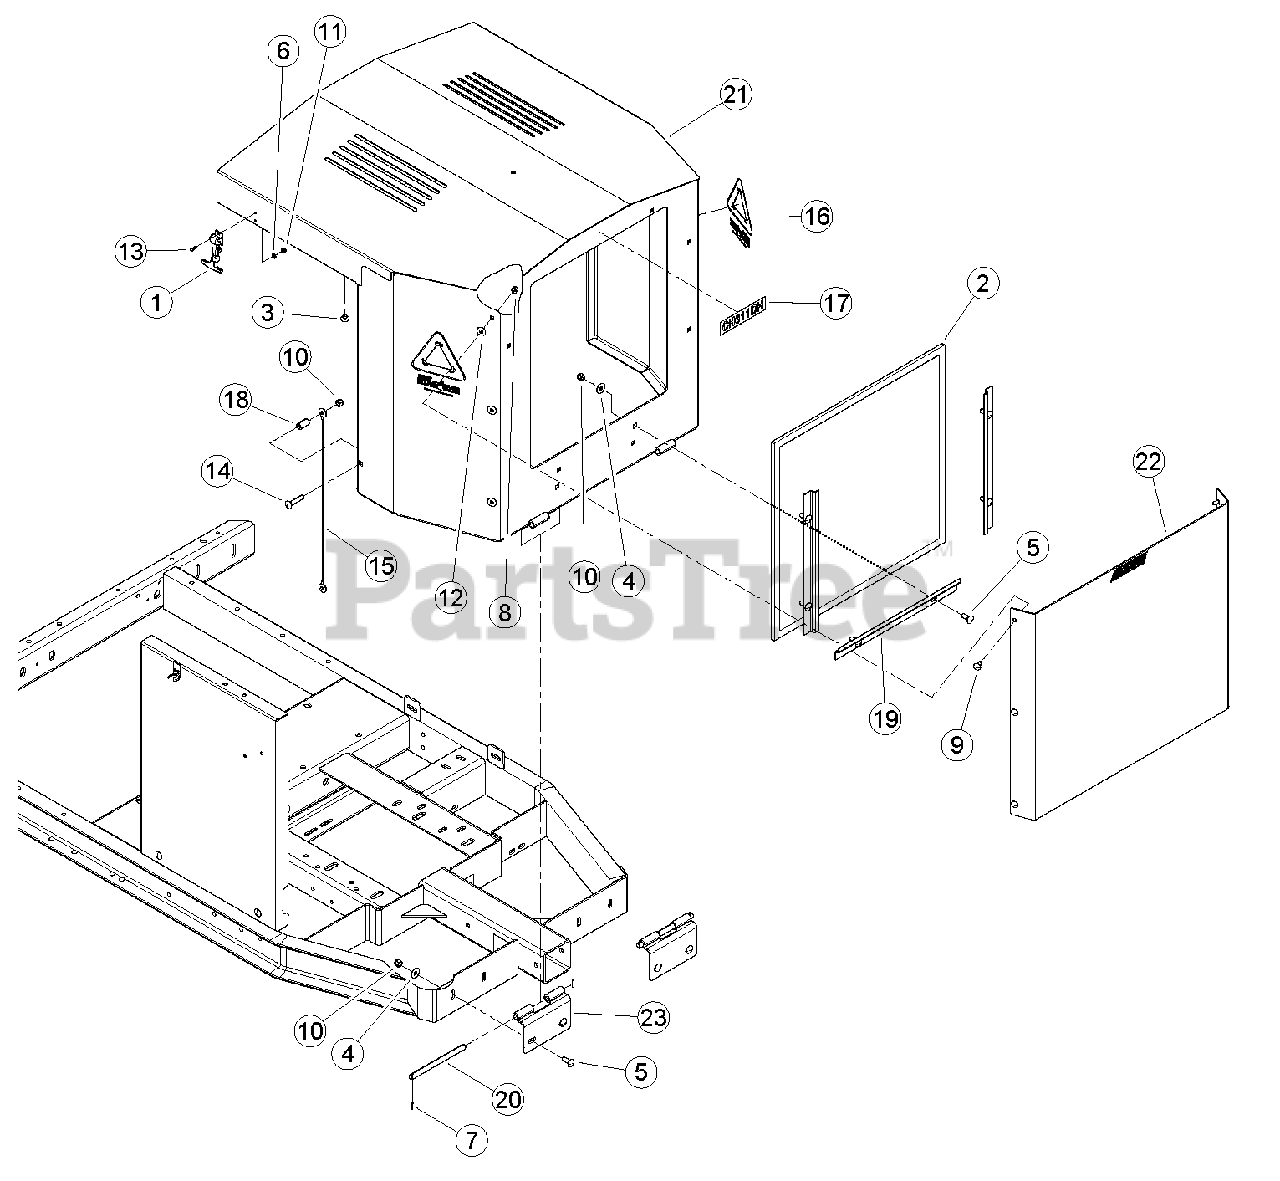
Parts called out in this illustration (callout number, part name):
1	LATCH, FLEXIBLE DRAW
2	SCREEN, RADIATOR INLET
3	BUMPER, RUBBER
4	WASHER, 3/8 FLAT ZP
5	BOLT, 3/8 X 1 CRG GR5 NC ZP
6	WASHER, 3/16 FLAT ZP
7	ROLL PIN, 5/32 X 3/4" PLAIN
8	NUT, 5/16 NE NYLOCK ZP
9	BOLT, 5/16 X 3/4 CRG GR5 NC ZP
10	NUT, 3/8 NE NYLOCK ZP
11	NUT, 10/24 NYLOCK TYPE NM, ZP
12	WASHER, 5/16"ID 7/8"OD NYLON FLAT
13	SCREW, 10-24 X 1/2 MCH PAN HD,PH ZP
14	BOLT, SHOULDER 1.88" LONG CRG GR5 ZP
15	LANYARD, STEEL W/PVC 1/8" X 20"
16	DECAL, CHIP IT
17	DECAL, MODEL CH611DH
18	IDLER SPACER
19	BRACKET, SCREEN HOLDER
20	PIN, HOOD HINGE PLATED
21	WELDMENT, 6 INCH HOOD
22	GUARD, 6" CHIPPER ROCK
23	WELDMENT, HOOD HINGE
